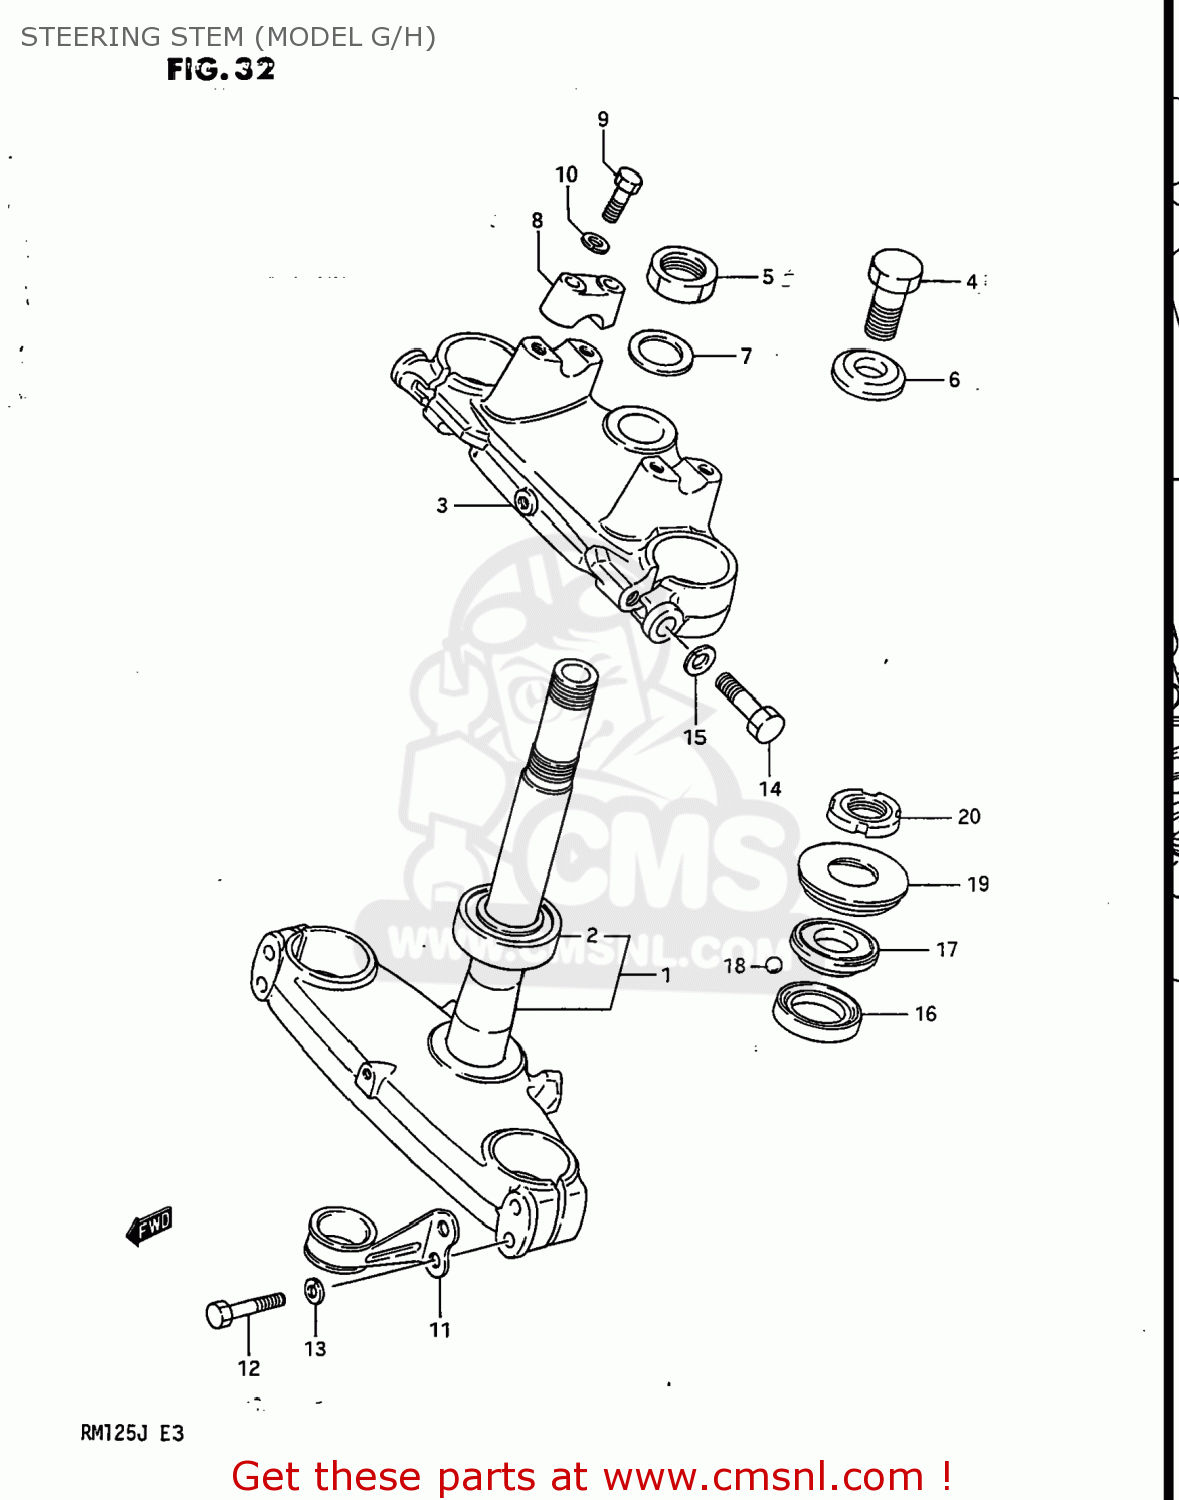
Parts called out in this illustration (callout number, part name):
1	STEM,STEERING
2	BEARING
3	HEAD,STEERING STEM
4	BOLT
5	NUT,STEERING STEM
6	WASHER
7	WASHER
8	HOLDER,HANDLEBAR
9	BOLT
10	LOCK WASHER
11	CLIP
12	BOLT 8X40
13	LOCK WASHER
14	BOLT
15	LOCK WASHER
16	RACE,STEERING INNER (SUJ)
17	RACE,STEERING,OUTER,UPPER
18	BALL
19	SEAL,STEERING UPR DUST
20	NUT,STEERING STEM
